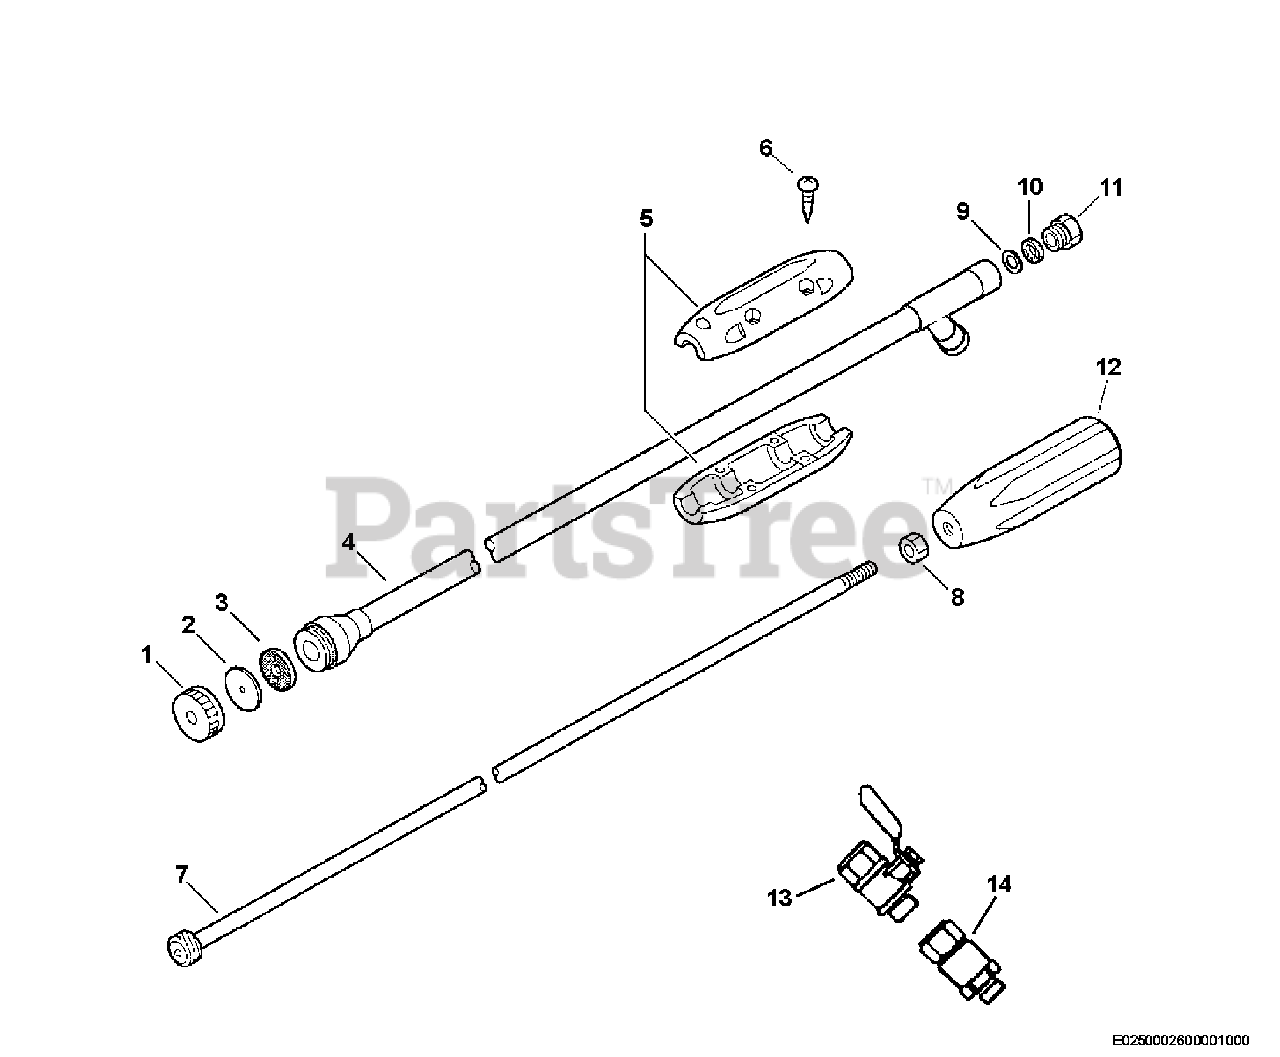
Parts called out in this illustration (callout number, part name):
1	CAP, NOZZLE
2	NOZZLE PLATE
3	NOZZLE GASKET
4	NOZZLE PIPE ASSY
6	SCREW - 4X18
7	ADJUSTMENT SHAFT ASSY
10	GASKET
13	PETCOCK
14	COUPLING, SWIVEL
